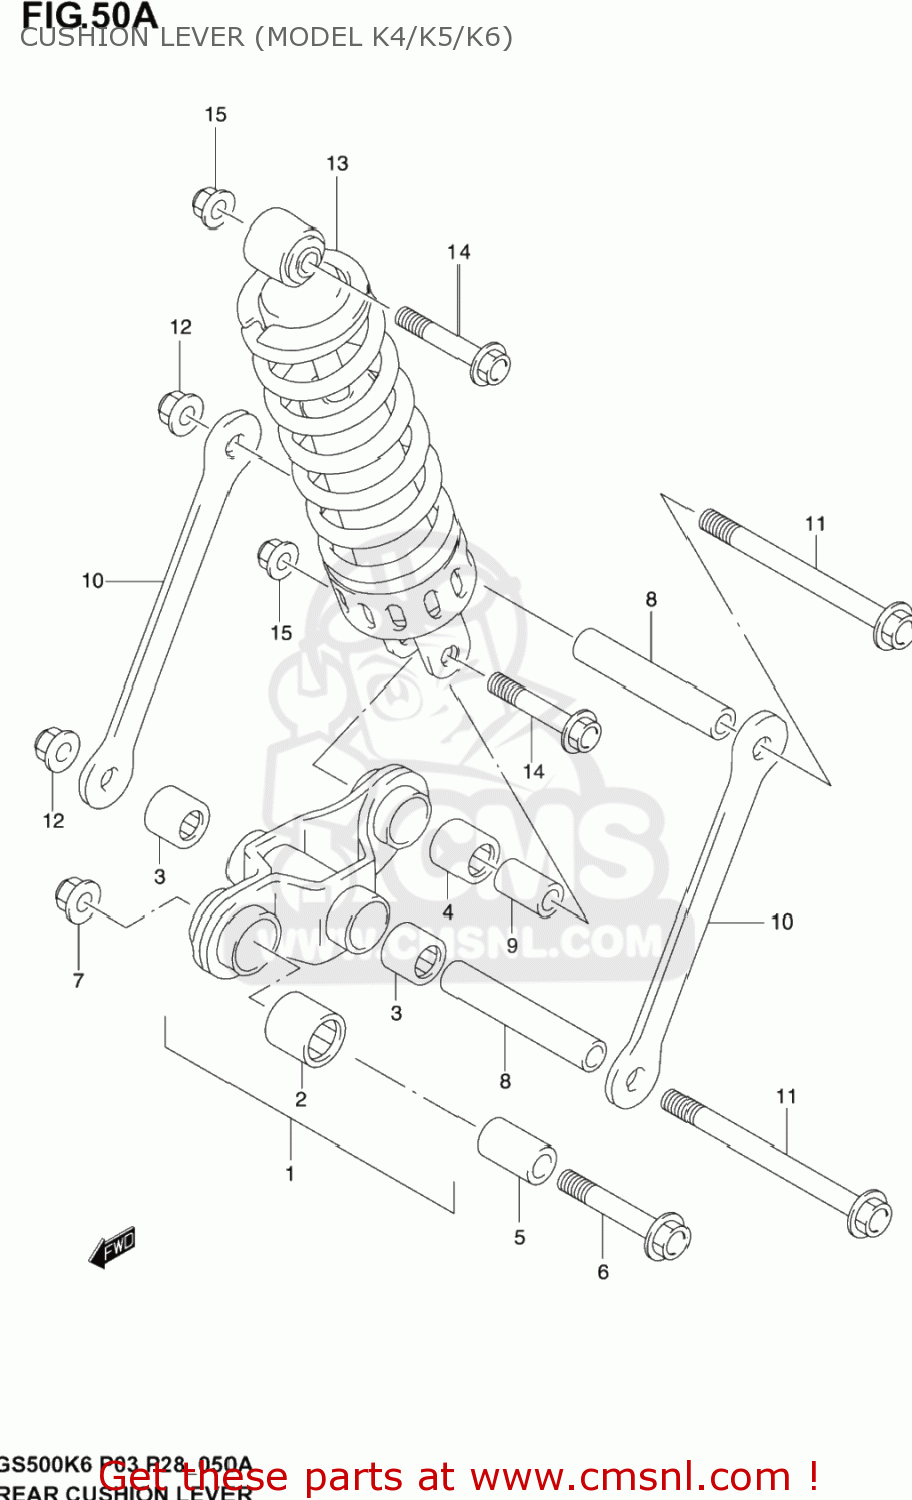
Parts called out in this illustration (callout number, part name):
1	LEVER SET,REAR
2	BEARING(20X27X26)
3	BEARING(17X24X25)
4	BEARING(17X24X26)
5	SPACER, FRONT (12X20X30)
6	BOLT(12X57)
7	NUT 12MM
8	SPACER(12X17X89)
9	SPACER, REAR (10X17X30)
10	ROD, REAR CUSHION
11	12
12	NUT 12MM
13	ABSORBER ASSY,RR SHOCK
14	BOLT(10X52)
15	NUT
